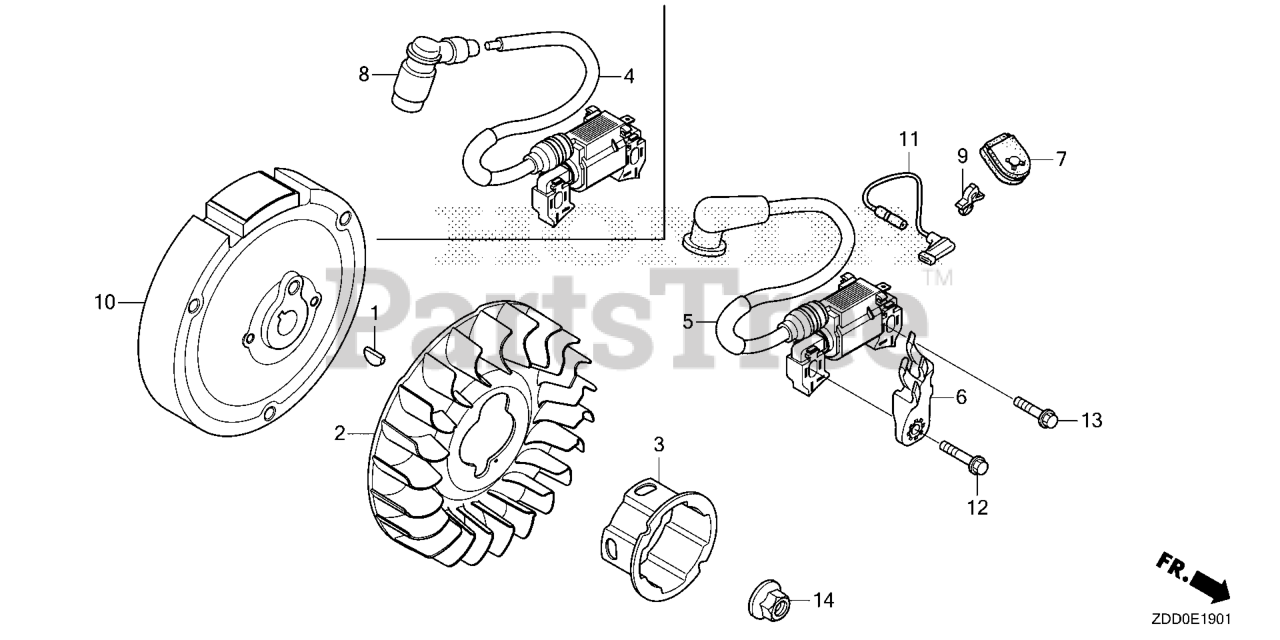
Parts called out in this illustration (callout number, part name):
1	KEY, SPECIAL WOODRUFF (25X18)
2	FAN, COOLING
3	PULLEY, STARTER
4	COIL ASSY., IGNITION
6	CLAMP, IGNITION WIRE
7	GROMMET, WIRE
9	CLIP, IGNITION WIRE (8MM)
11	WIRE, STOP SWITCH
12	BOLT (6X30) (CT200)
13	BOLT, FLANGE (6X25) Use up to Engine SN 2056819.
14	NUT, SPECIAL (14MM)
